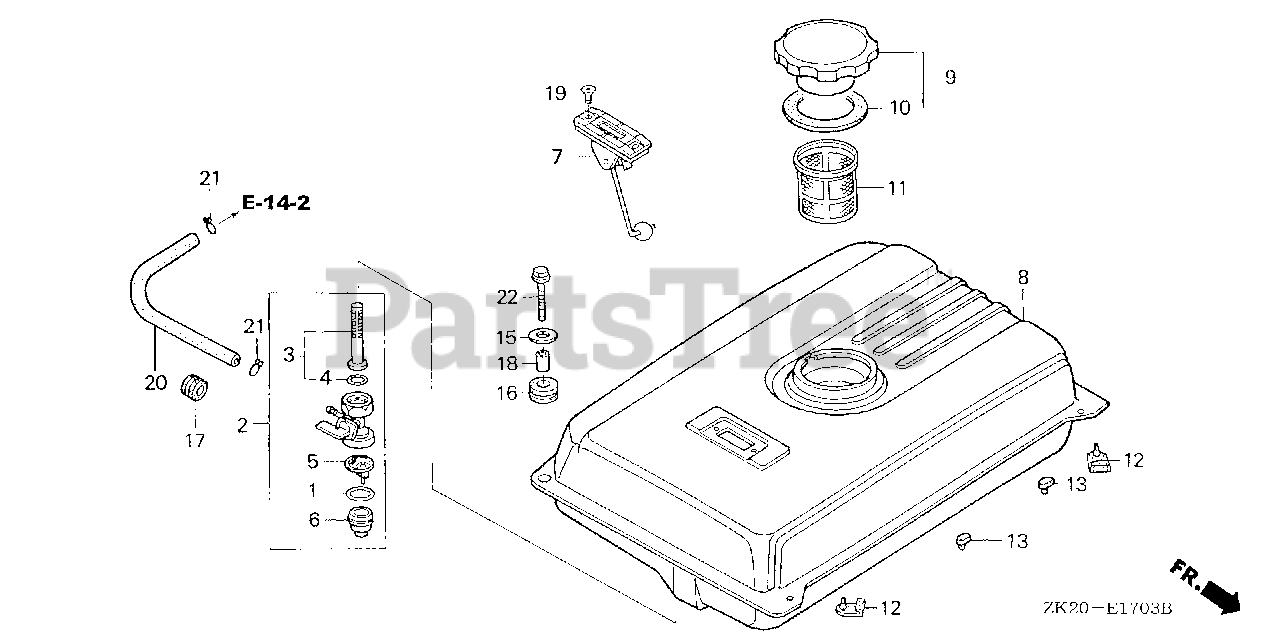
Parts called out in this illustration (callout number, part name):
1	GASKET, FUEL STRAINER CUP
2	PETCOCK ASSY.
3	SCREEN SET, FUEL STRAINER
4	O-RING (9.0X1.3)
5	FILTER, CUP
6	CUP, FUEL STRAINER
17	RUBBER, FUEL (9X15X10)
20	BULK HOSE, FUEL (4.5X3000) (4.5X190)
21	CLIP, TUBE (B8)
